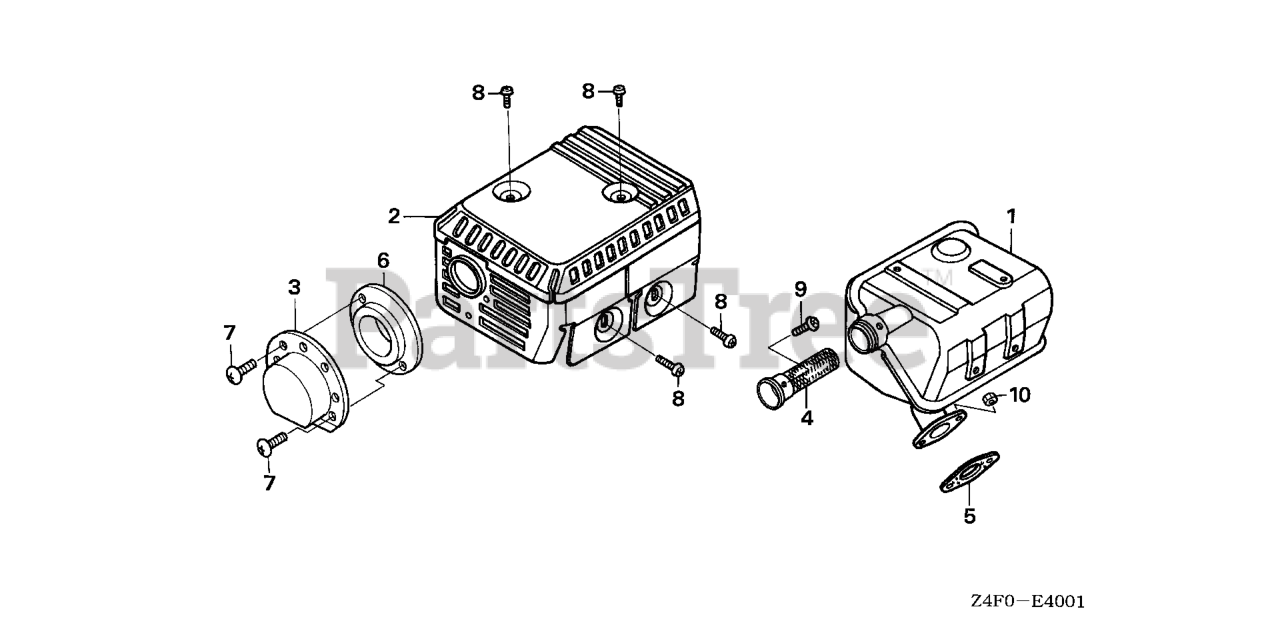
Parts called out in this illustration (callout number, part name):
3	DEFLECTOR
6	GUIDE, MUFFLER
7	SCREW, TAPPING (4X8)
